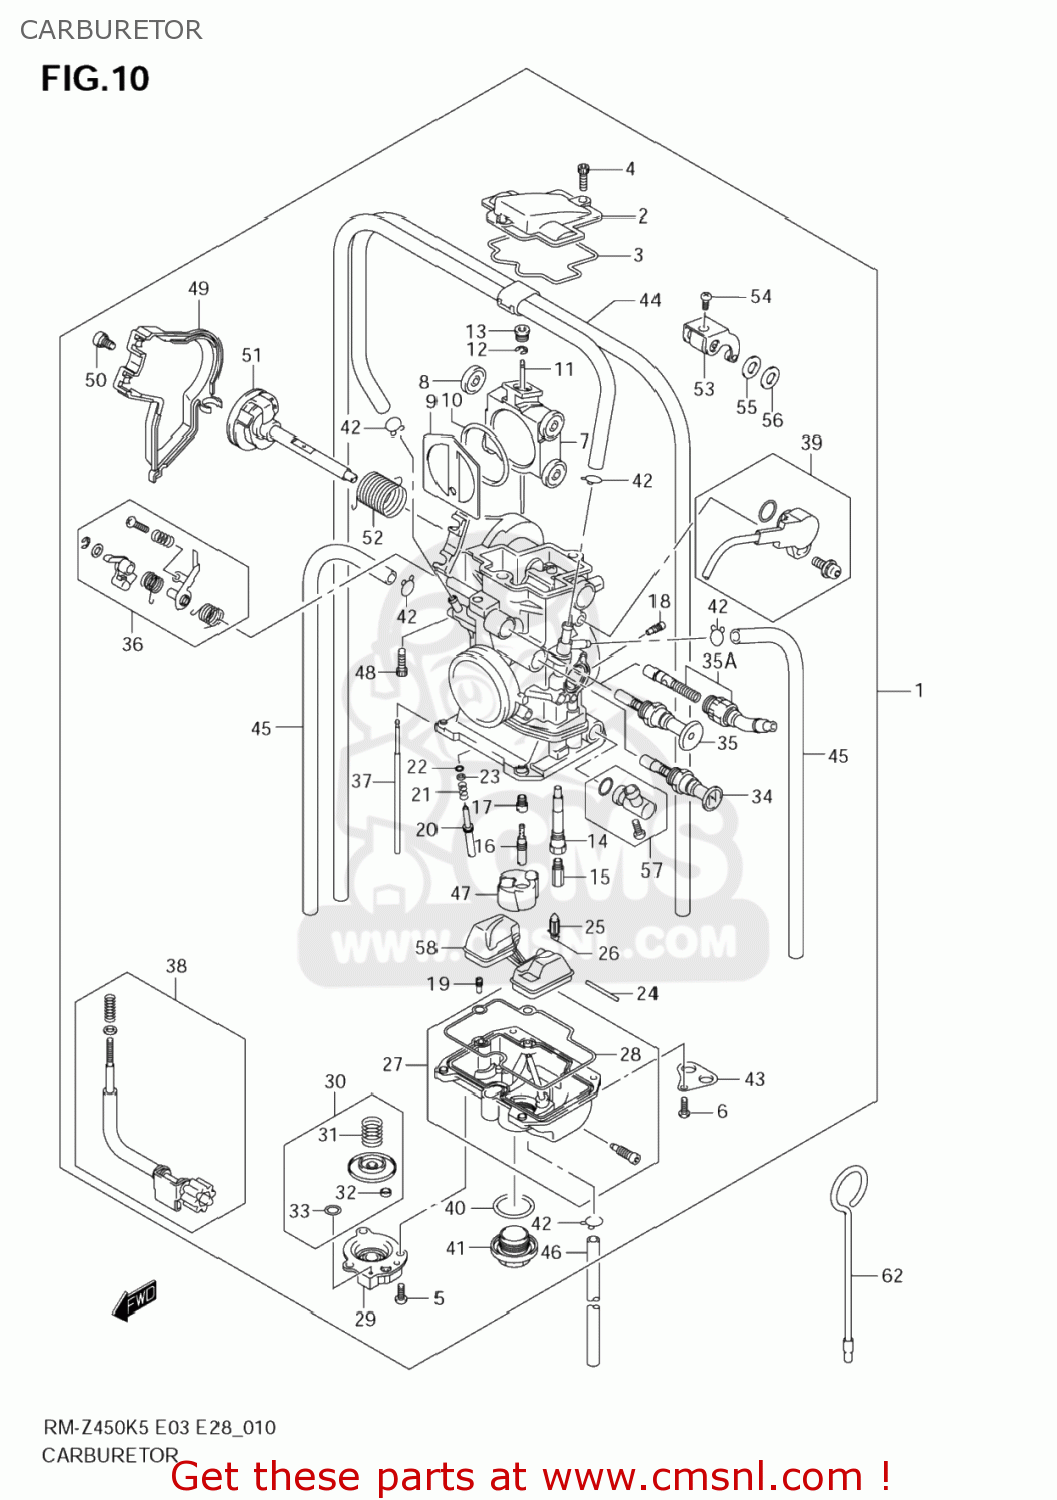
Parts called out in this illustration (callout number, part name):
1	CARBURETOR ASSY
2	TOP
3	O RING
4	BOLT
5	6
6	SCREW
7	THROTTLE VALVE
8	9
9	FLOATING VALVE
10	LIP SEAL
11	NEEDLE,JET
12	13
13	SCREW SET,JET,NEEDLE
14	MAIN NOZZLE
15	JET,MAIN(170)
16	JET,SLOW(42)
17	JET,STARTER
18	JET,SLOW AIR
19	JET,ACC
20	SCREW,ADJUST
21	SPRING
22	O RING
23	WASHER
24	25
25	VALVE,FLOAT
26	CLIP
27	FLOAT,CHAMBER BODY SET
28	O RING
29	COVER
30	DIAPHRAGM SET
31	U RING
32	SPRING
33	O RING
34	STARTER VALVE
35	STARTER VALVE
35A	STARTER VALVE
36	LEVER SET,PUMP
37	ROD
38	SCREW SET
39	SENSOR SET,THROTTLE
40	O RING
41	BOLT,DRAIN
42	43
43	PLATE
44	PIPE SET,BOWL VENT
45	PIPE
46	PIPE
47	PLATE,BUFFER
48	SCREW
49	COVER
50	BOLT
51	THROTTLE SHAFT
52	SPRING
53	LINK ARM
54	SCREW
55	WASHER
56	WASHER
57	JOINT SET
58	FLOAT
59	59-3
60	61-1
61	NEEDLE,JET
62	HOLDER,JET NEEDLE
